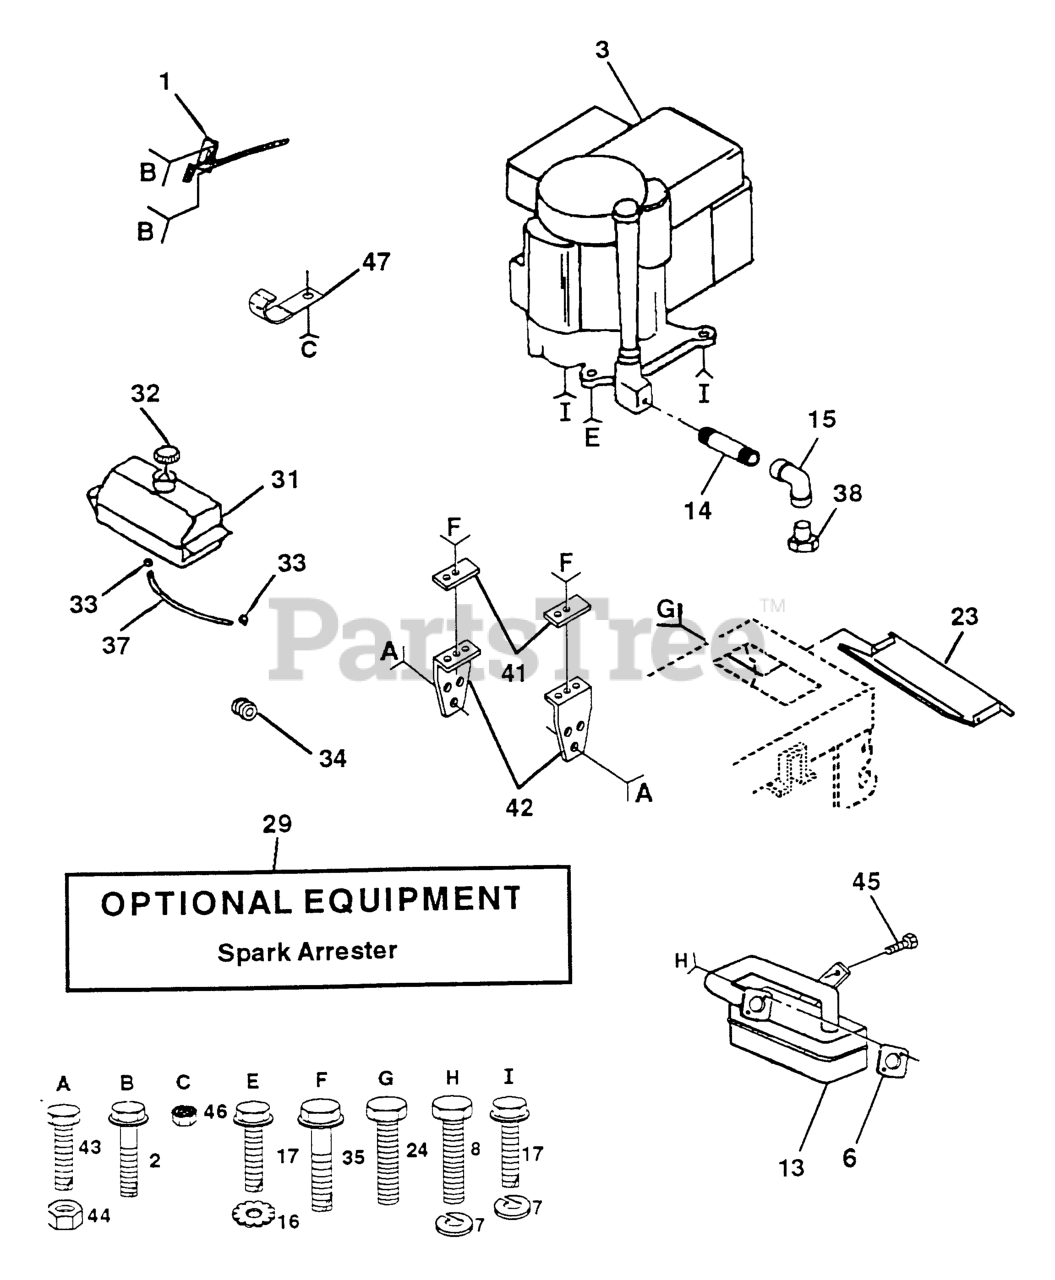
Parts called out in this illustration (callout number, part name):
1	THROTTLE CONTROL
2	SCREW LT
6	Gasket, Eng
7	WASHER.LOCK.HVY.HLCL.SPR.5/16
8	Bolt, Fin Hex 5/16-18 X 5/8
13	MUFFLER LT 12.5
14	Nipple Pipe 3/8 Npt X 3-1/2"
15	ELBOW
16	WASHER EXT TOOTH LOCK 5/16
17	BOLT, HEX
23	HEAT SHIELD
29	KIT, SPARK ARREST
31	TANK FUEL LT
32	GAS CAP
33	HOSE CLAMP
34	BUSHING.SNAP.NYL.BLK.
35	SCREW
37	FUEL LINE T
38	Plug Oil Drain
41	CLAMP, FUEL TANK T
42	BRACKET FUEL TANK T
43	BOLT
45	Bolt, Hex
47	CLIP T
